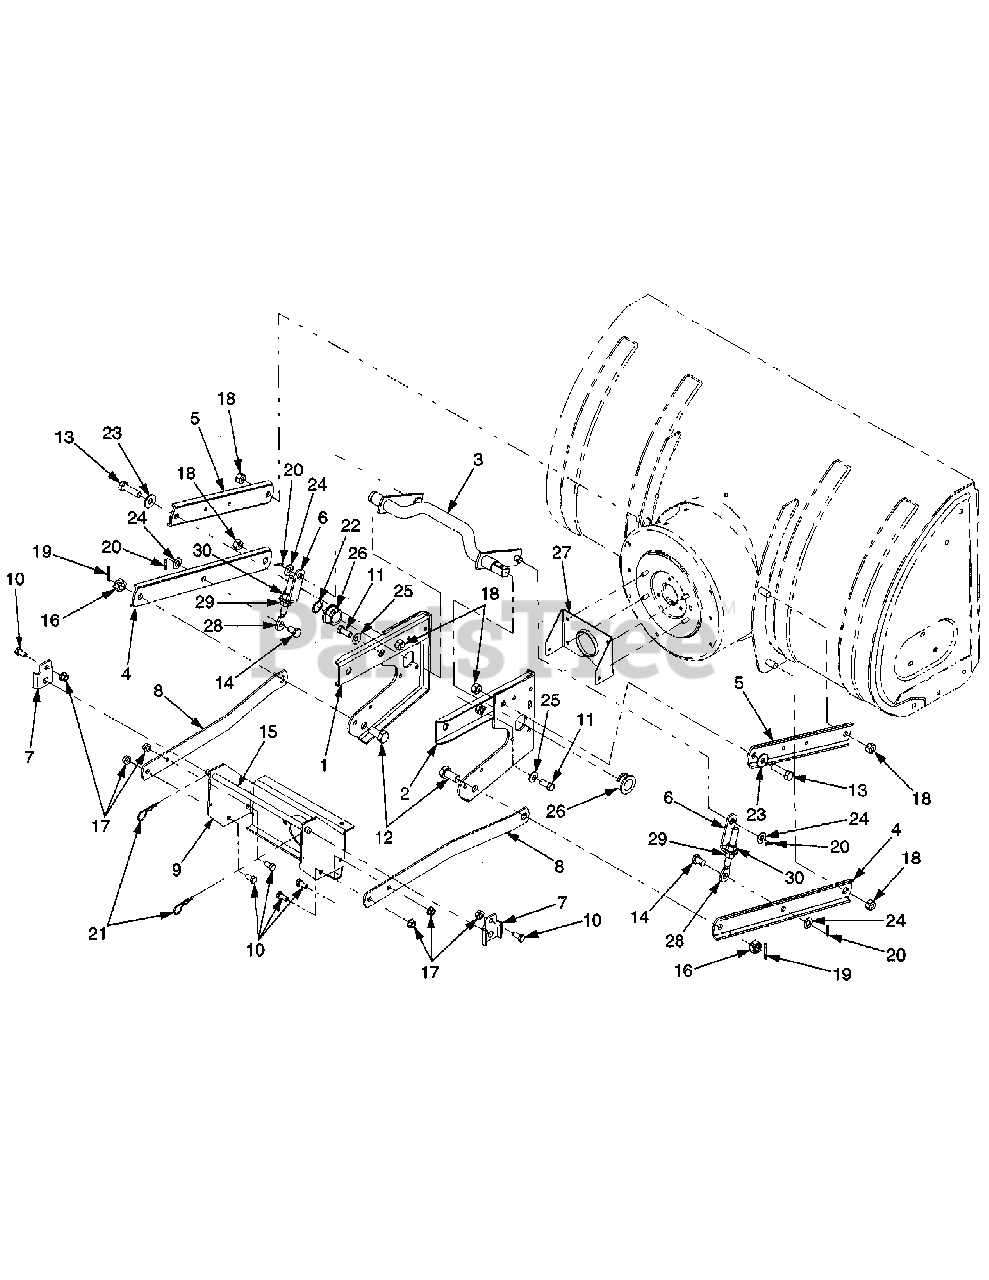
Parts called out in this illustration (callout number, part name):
1	Hitch Plate. RH
2	Hitch Plate. LH
3	Rockshaft Assembly. Lift
6	Link. Lift (Mfg . Code 1 H262G & After)
7	Bracket. Frame Mounting
8	Arm. Subframe
9	Bracket. Gearbox Mounting
10	Screw. Hex Cap. 3/8-16 x .75 GR5
11	Screw. Hex Cap. 7/16-14 x 1.0 GR5
12	Screw. Hex Cap. 5/8-18 x 1.31 GR5
13	Screw. Hex Cap. 1/2-13 x 1.75 GR5
14	Pin. Clevis. . 5 x . 78 Lg
15	Rod..5x12.5Lg
16	Nut. Hex Slotted. 518-1 8
17	Nut. Hex Flange Lock. 3/8-16
18	Nut. Hex Center Lock. 112-1 3
19	Pin. Cotter. 118 x 1.25
20	Pin. Cotter Bow Tie
21	Pin. Internal Cotter
22	Ring. Snap. 1.0 Dia . Shaft
23	Washer. Flat. . 531 x 1.25 x . 10 .
24	Washer. Flat. . 510 x 1.0 x . 062 .
25	Washer. Bell. . 45 x 1 0 . x . 062 ...
26	Bearing. Flange w/Flats
27	Bracket. Box Mounting
28	Link. Adjustment (Mfg . Code 1H262G & After)
29	Nut. Hex. 1/2-13 GR5 (Mfg . Code 1H262G & After)
30	Nut. Hex Insert Lock. 1/2-13 GR8 (Mfg. Code 1H262G & After)
